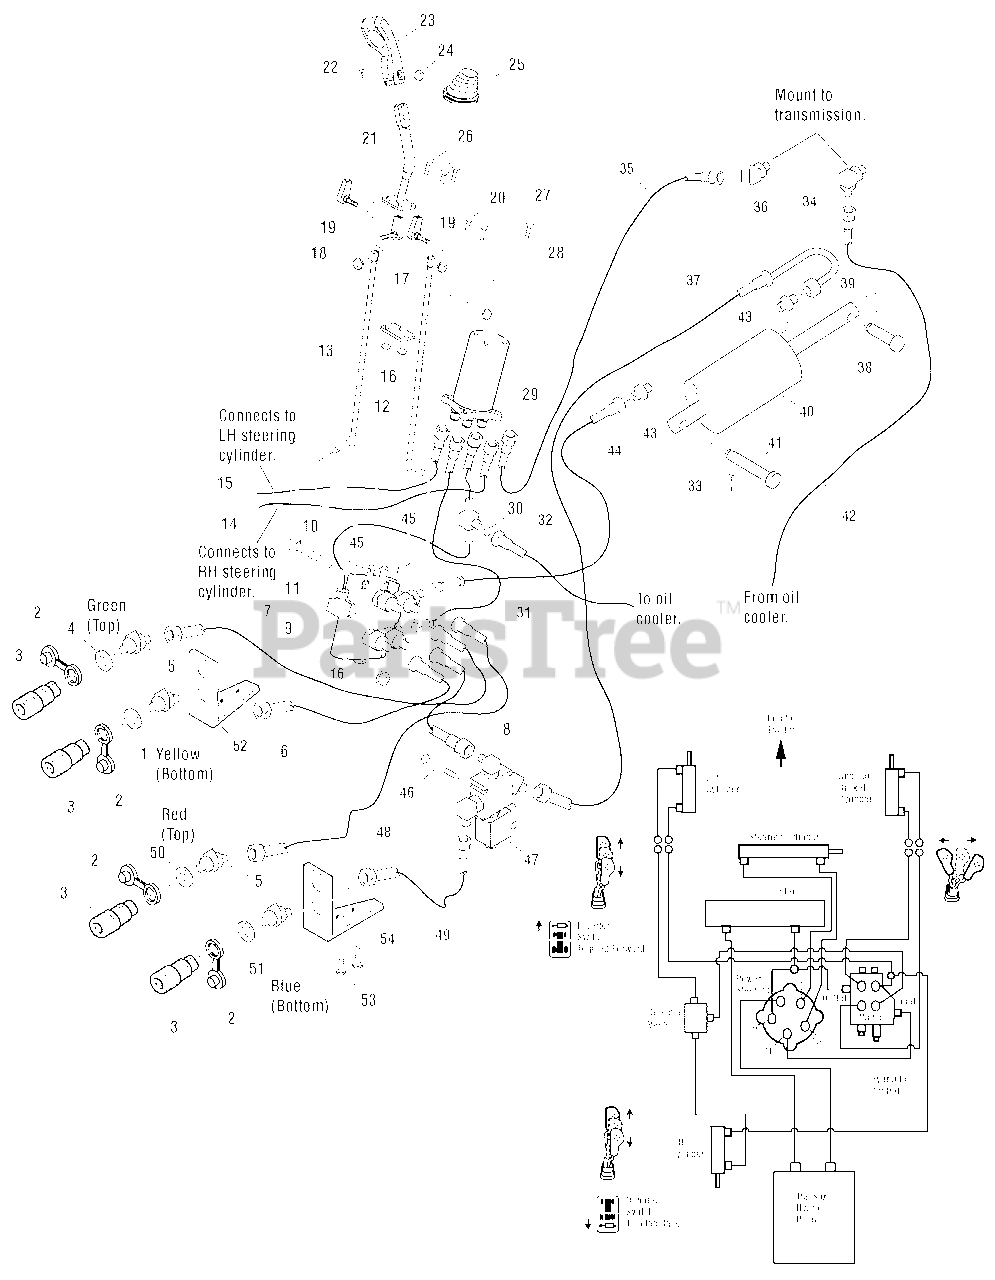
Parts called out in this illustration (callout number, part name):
2	PLUG, Plastic
3	BODY ASSEMBLY, Coupler 1/4-18 Int, 1.94 LG
5	FITTING, Tube Elbow
6	TUBE, Hydraulic
7	TUBE, Hydraulic
8	TUBE, Hydraulic
9	VALVE ASSEMBLY, Control 2 Spool
10	TUBE, Hydraulic
11	CARRIAGE BOLT, 1/4-20 x 2 G5
12	ROD & PIN ASSEMBLY, Control
13	ROD & PIN ASSEMBLY, Control
14	HOSE ASSEMBLY, Hydraulics, R.H.
15	HOSE ASSEMBLY, Hydraulics, L.H.
16	NUT, Hex 1/4-20 Conical Washer
17	PAD, Hydraulic
18	NUT, Hex, Spiralock Flange 1/4-28
19	JOINT, Ball, 1/4-28 Int
20	CAPSCREW, Hex Head, 1/4-20 x 3/4 G5
21	LEVER ASSEMBLY, Joystick
22	SCREW, TORX PLUS Socket Head, 1/4-20 x 7/8
23	HANDLE, Cruise 3/8 x 7/8 Slot
24	NUT, Hex, Lock, ESNA LIGHT, 1/4-20 NC-3B
25	BOOT, Hydraulic Control
26	SCREW, Hex SEMS Square Washer, 1/4-28 x 3/4
27	CAPSCREW, Hex Head
28	LOCKWASHER, Spring
29	POWER STEERING UNIT
31	TUBE, Hydraulic
32	HOSE ASSEMBLY, Hydraulic Rubber, 29 LG, 1 Swivel
33	CLIP, Hair Pin
34	FITTING, Tube Elbow 9/16-18 13/16-16, 90 Degrees
35	TUBE, Assembly Hydraulic
36	FITTING, Tube Elbow, 9/16-18 11/16-16, 90 Degrees
37	HOSE ASSEMBLY, Hydraulic Rubber, 180 Degrees
38	PIN, Round Head Drilled, 1/2 x 2-1/2
39	PIN, Cotter, 1/4 x 1
40	CYLINDER ASSEMBLY, Hydraulic
41	PIN, Clevis
42	HOSE, Hydraulic
43	TUBE, Fitting Mail 1/8 NPT+7/16-20 .250TU
44	HOSE ASSEMBLY, Hydraulic Rubber, 13.7 LG, 30 Degrees
45	CLIP, Hair Pin
46	SCREW, Hex, Washer Head Taptite, 1/4-20 x 1-3/4
47	VALVE ASSEMBLY, Selector
48	TUBE, Hydraulic
49	TUBE, Hydraulic
52	SUPPORT, Quick Disc R.H.
53	SCREW, Hex Lock Flange 1/4-20 x 3/4
54	SUPPORT, Quick Disc L.H.
